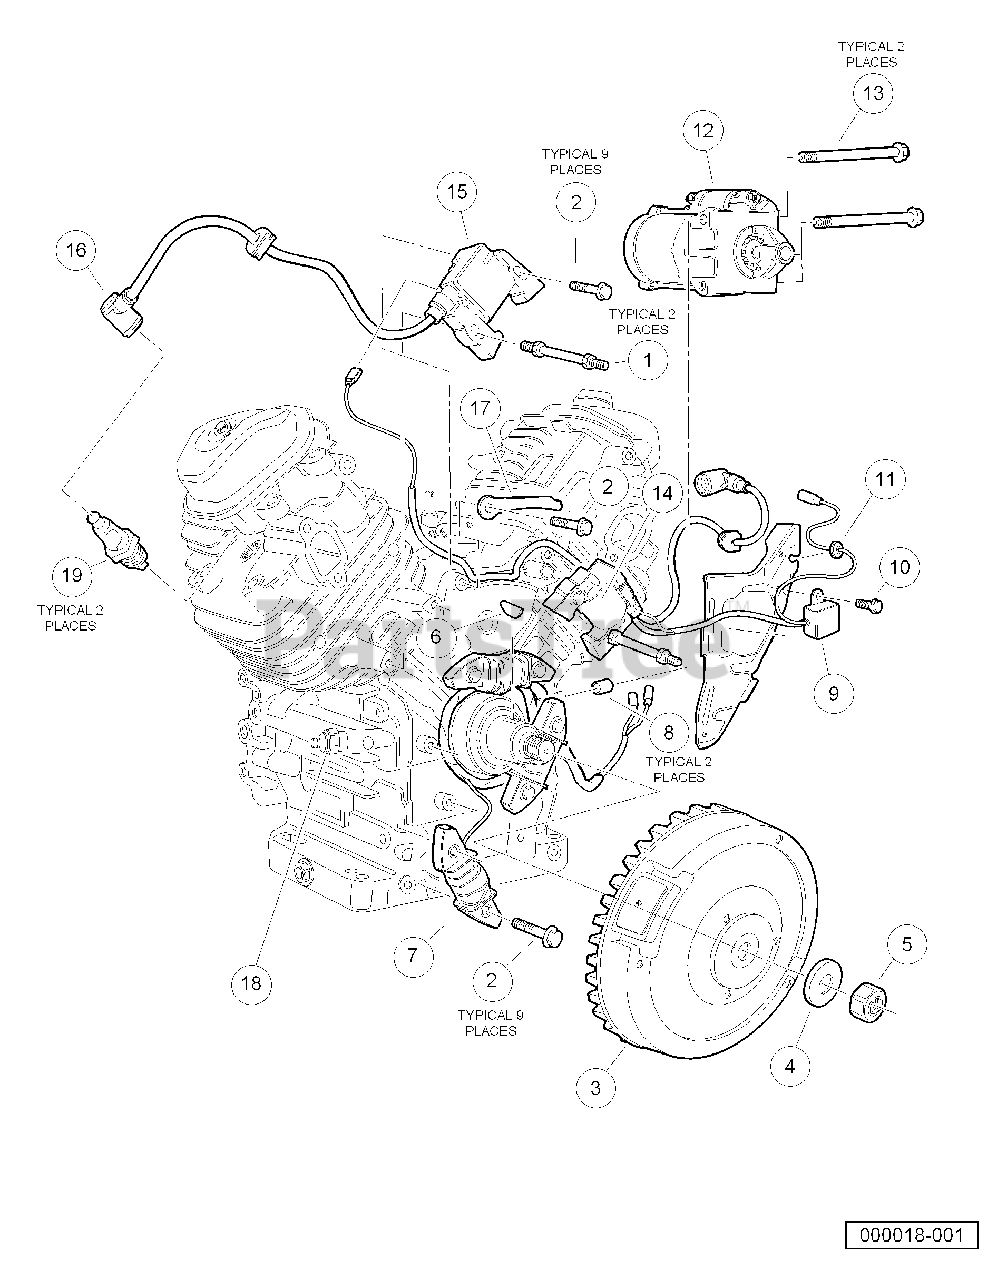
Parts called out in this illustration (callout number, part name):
1	Stud, Engine
2	Bolt, Flange Head, M6 X 1 X 32
4	Washer, M20
5	Nut, Flange, M20
6	Key, Special Woodruff, 25 X 18
7	Coil Assy, Charge, 12-Volt, 20-Amp
8	Pin, Dowel, 10x12
9	Diode Assembly
10	Bolt, Flange Head, M6 X 1 X 8
11	Grommet, Tool
12	Motor, Starter
13	Bolt, Flange Head, M8 X 1.25 X 110
14	Coil Assy, R, Ignition
15	Coil Assy, L, Ignition
16	Cap Assy, Noise Suppressor
17	Clamp, Wire
18	Switch, Oil Pressure
19	Spark Plug, BPR2ES
